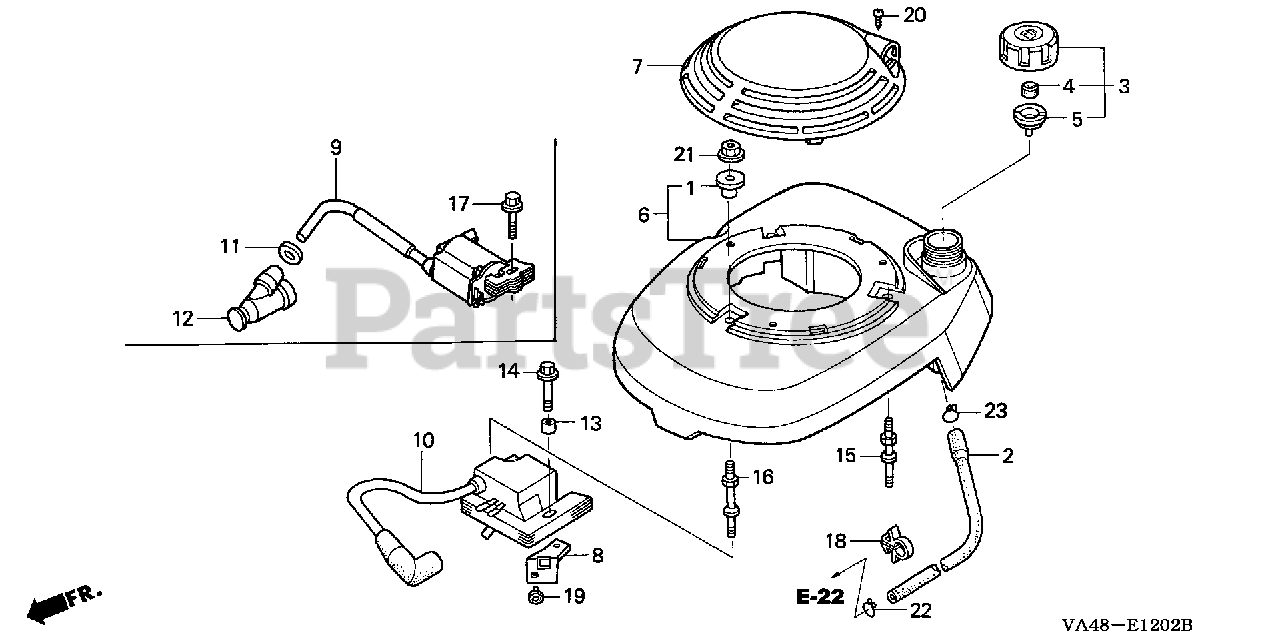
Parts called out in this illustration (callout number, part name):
1	COLLAR, AIR CLEANER (TOYO ROKI)
2	TUBE, FUEL TANK (135MM)
2	BULK HOSE, FUEL (5.5X3000) (Honda Code 5338587). (5.5X150)
3	CAP ASSY., FUEL TANK
4	SPONGE, FUEL CAP BREATHER
5	GASKET, FUEL CAP
6	COVER, FAN
7	HOOD, FAN COVER *R8* (SMOOTH) (BRIGHT RED)
7	HOOD, FAN COVER (GLOSSY FINISH)
8	GUIDE, FAN COVER
10	COIL ASSY., IGNITION
13	COLLAR, ROTO-STOP
14	BOLT, FLANGE (6X32)
15	BOLT, STUD (BRAKE)
16	BOLT C, STUD
18	CLIP B, CABLE
19	GROMMET, DEFOGGER CORD (15MM)
20	SCREW, TAPPING (4X20)
21	NUT, FLANGE (6MM)
22	CLIP, TUBE (B8)
22	CLIP, TUBE (B10)
23	CLIP, TUBE (B10)
